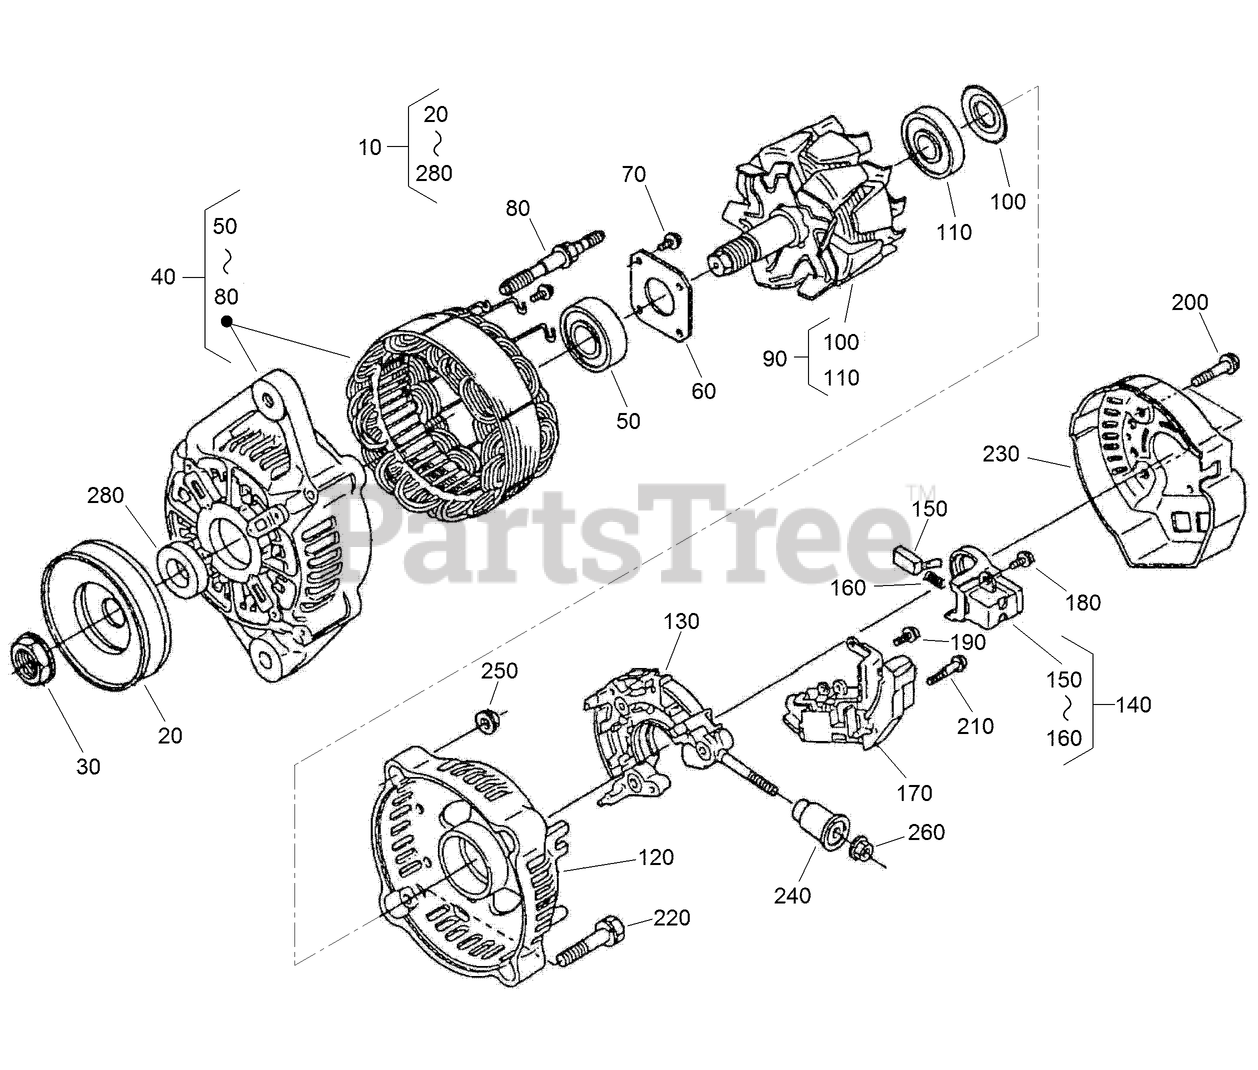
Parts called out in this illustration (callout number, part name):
10	60 AMP ALTERNATOR ASM
20	PULLEY-DYNAMO
40	DRIVE END FRAME ASM
50	BEARING
60	PLATE-RETAINER
70	SCREW-HEAD, ROUND
80	BOLT-THROUGH
90	ROTOR ASM
100	COVER-BEARING
110	BEARING-BALL
120	FRAME-END
130	HOLDER
140	BRUSH HOLDER ASM
150	BRUSH
160	SPRING-BRUSH
170	REGULATOR ASM
180	SCREW-HEAD, ROUND
190	SCREW-HEAD, ROUND
210	SCREW-HEAD, ROUND
230	COVER-END
240	INSULATION-BRUSH
280	COLLAR
